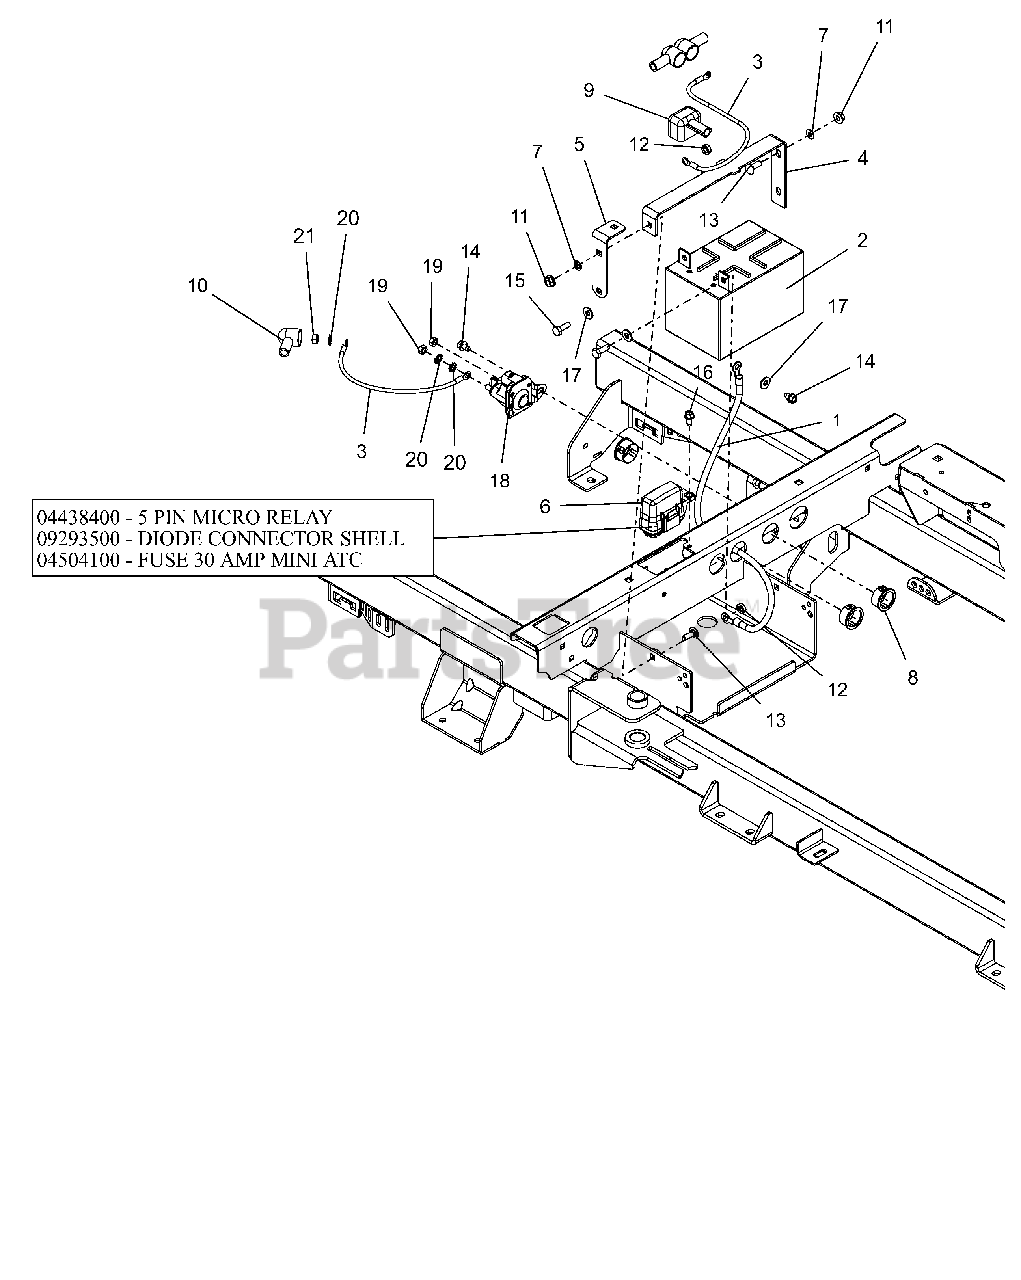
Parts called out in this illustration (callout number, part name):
1	CABLE-NEGATIVE BATTERY 24.00"
2	BATTERY, 12V 12A-190CCA
3	CABLE,POS W/2 1/4 RING 15.0 LG
4	BRKT, BATTERY HOLD-DOWN
5	BRKT, BATTERY HOLD DOWN
6	HARNESS, WIRE-4POS KEY IKON/ZT
6	RELAY,MICRO5 TERML W/RESISTOR
6	DIODE, CONNECTOR SHELL
6	FUSE,30 AMP MINI-ATC
7	NUT-PUSH .25X.50 O.D.
8	BSHG, PANEL SNAP .937X1.11X.56
9	INSULATOR
10	BOOT, EYELET TERMINAL
11	NUT-LK-TOP-FLG .250-20 GF ZCC
12	NUT-KEPS .250-20
13	BLT, RHSN .25-20X.750 G5 ZCC
14	SCR,TAP .25-20X.375 HWH TR ZCC
15	BLT, HEX .25-20X.75 G5 ZCC
16	SCR-TAP .25-20X.50 HWH ZCC
17	WSHR,FLT .281X.625X.065 ZCC
18	SOLENOID, STARTER (SEALED)
19	NUT-STD M6-1.0 ZCC
20	WSHR,LK-EXT.262X.502X.026 ZCC
21	NUT-STD .250-20 G2 ZCC
